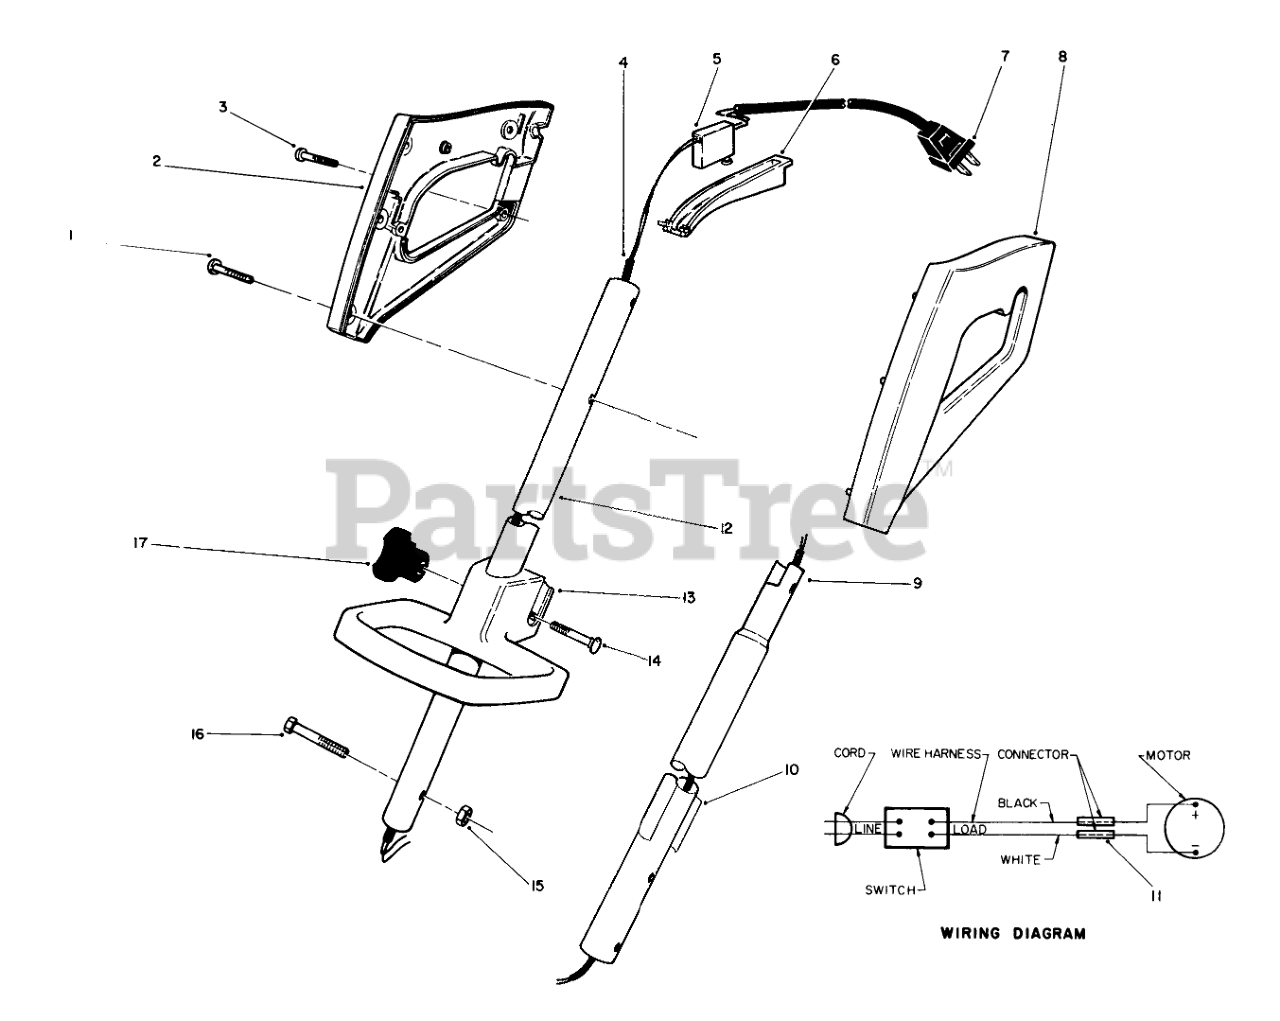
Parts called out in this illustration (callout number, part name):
1	Screw
2	Grip R.H.
3	SCREW-PPH
4	WIRE HARNESS
5	SWITCH
6	Bar Switch
7	DRIVE COUPLING
8	Grip-L.H.
9	TUBE-LOWER
10	Decal-CSA
11	CONNECTOR WIRE JOINT
12	TUBE-UPPER
13	Handle
14	BOLT-CARR
15	NUT-LOCK, NI
16	HEX HD MACHINE SCREW
17	Knob
